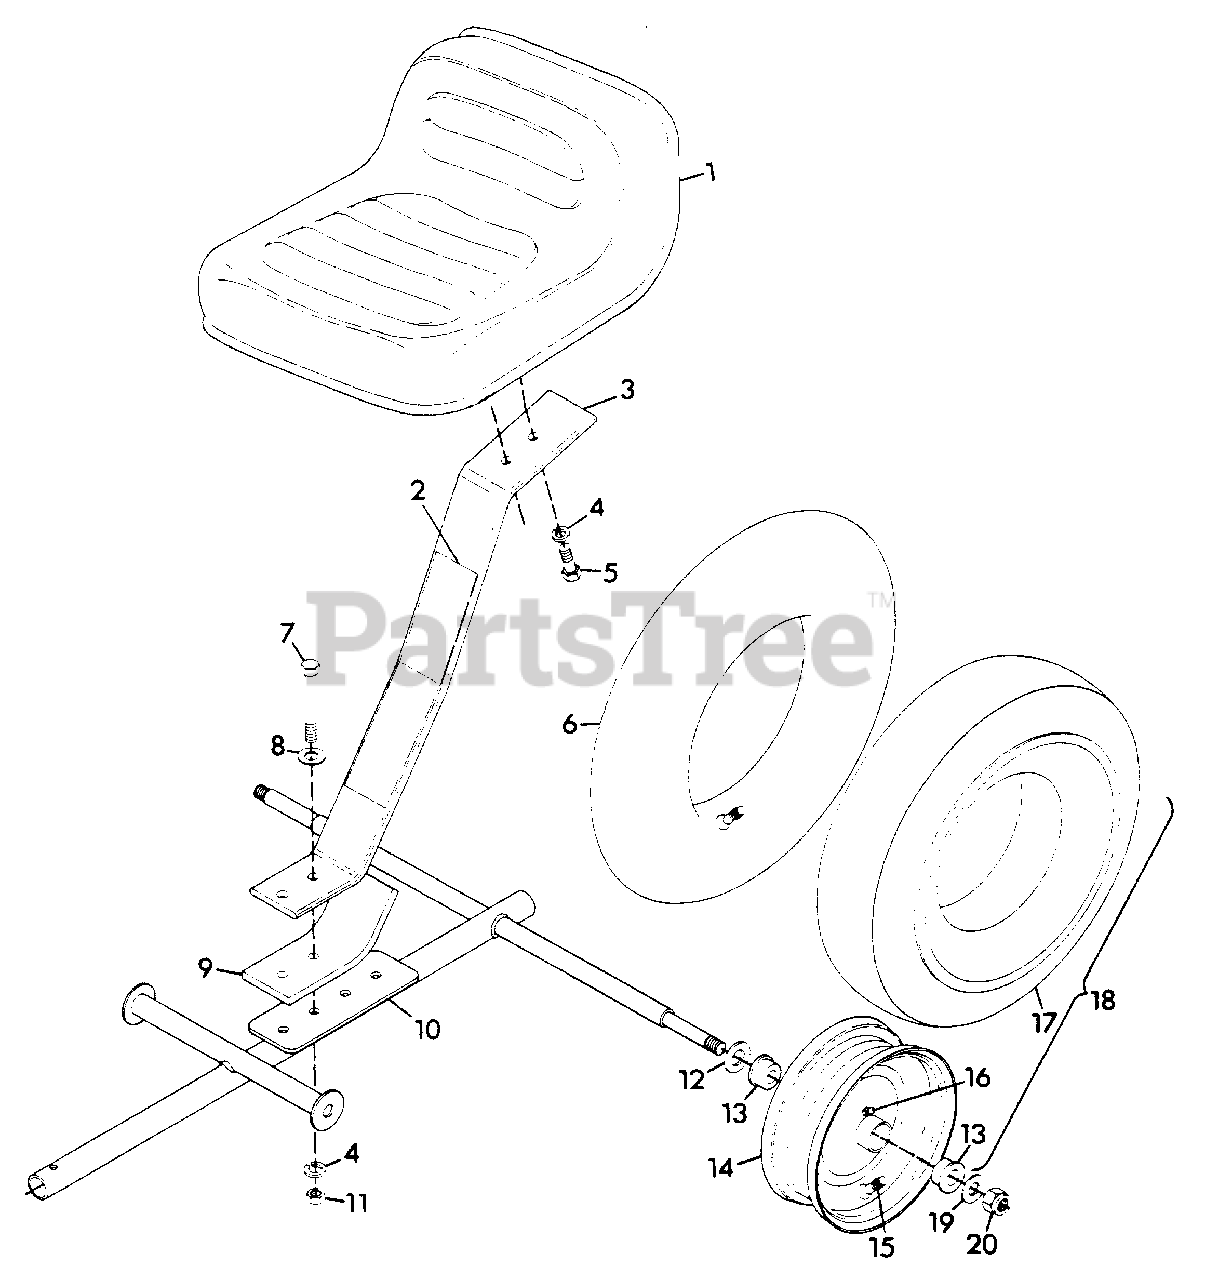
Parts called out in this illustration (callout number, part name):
1	SEAT, STEERING SULKY
2	DECAL, WARNING
3	ASSEMBLY, SEAT SPRING AND DECAL
4	WASHER, LOCK 1/2-13 REG.
5	BOLT, HEX 1/2-13X1.00
6	TUBE
7	BOLT, HEX 1/2-13X3.50
8	WASHER, FLAT .563X1.375X.109
9	PLATE, REINFORCEMENT
10	ASSEMBLY, CHASSIS RIDING SULKY
11	NUT, JAM 1/2-13 HEX
12	WASHER, FLAT .812X1.496X134
13	BUSHING, WHEEL
14	WHEEL, ASSEMBLY LESS TIRE/TUBE
15	ASSEMBLY, VALVE STEM
16	FITTING, LUBE 1/4-28
17	TIRE
18	WHEEL, SULKY ASSEMBLY COMPLETE(INCLUDES ITEM NOS. 13,14,15,16,17)
19	WASHER, FLAT .656X1.312X.095
20	NUT, LOCK 5/8-18 L.T.
